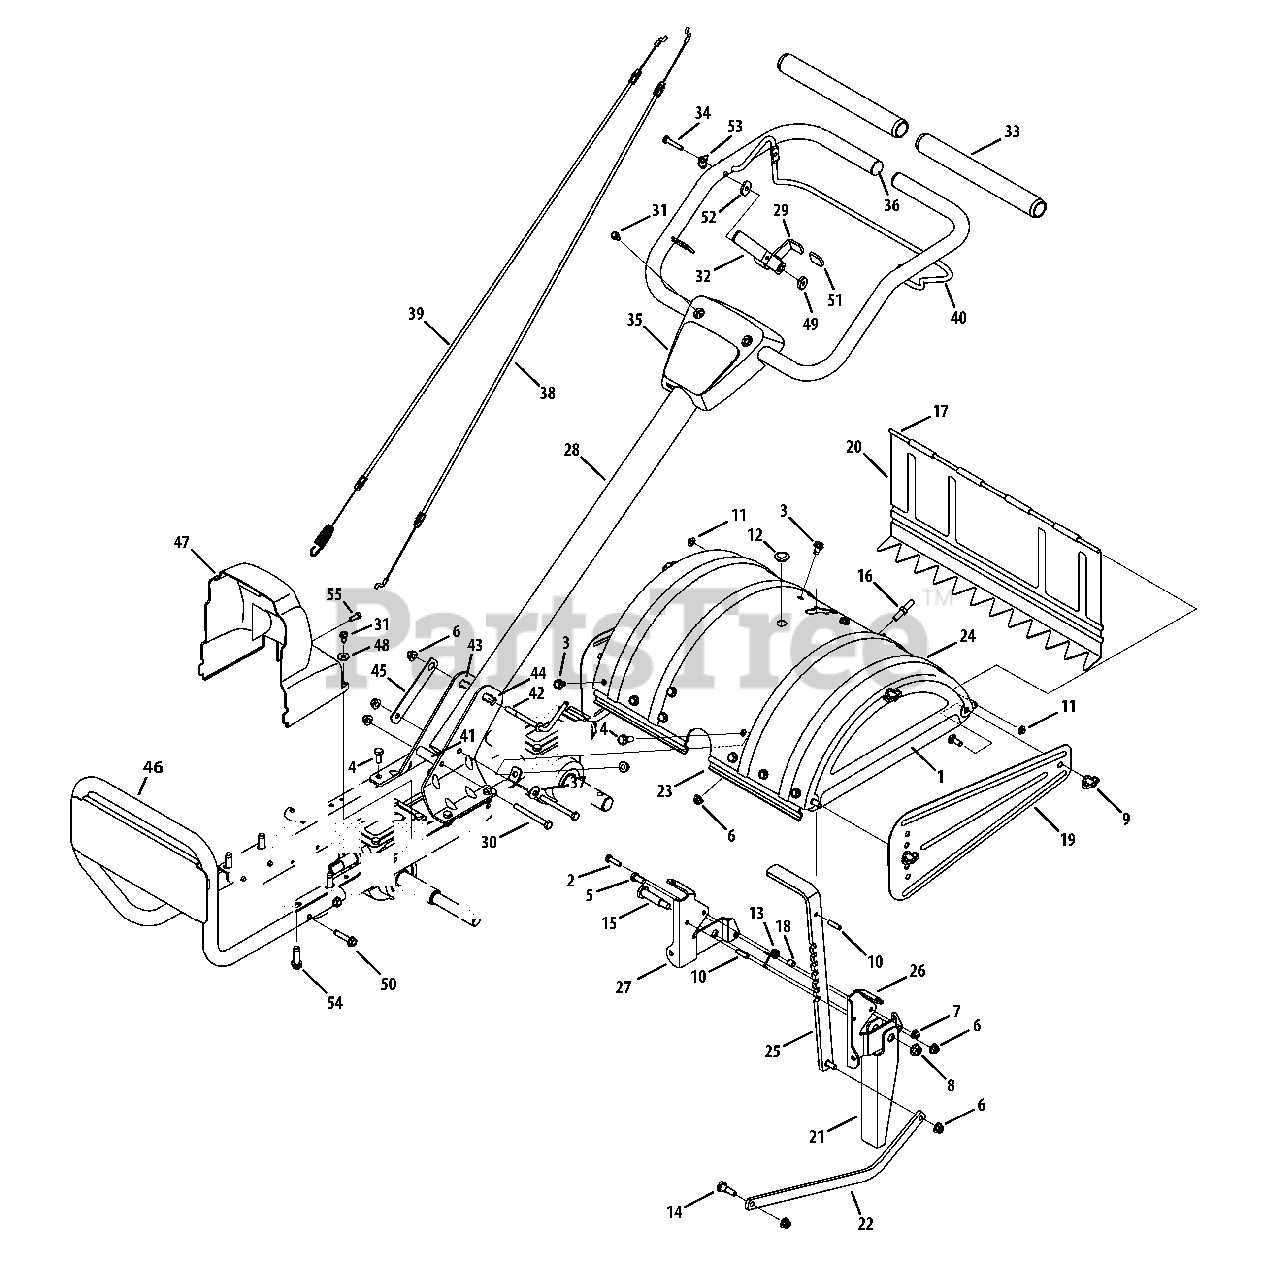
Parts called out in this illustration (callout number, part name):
1	End Cover Assembly
2	Hex Head Screw, 1/4-20 x 1
3	Hex Head Screw, 5/16-18 x .625
4	Hex Head Screw, 5/16-18 x .875
5	Hex Head Screw, 5/16-18 x .75
6	Nylon Hex Lock Nut, 5/16-18
7	Nylon Hex Lock Nut, 1/4-20
8	Flange Lock Nut, 3/8-16
9	Wing Nut, 5/16-18
10	Spirol Pin
11	Cap Nut, 1/4 Rod
13	Torsion Spring
14	Shoulder Screw, .405 x .435 5/16-18
15	Shoulder Screw, .498 x 1.635
16	Stop Screw
17	Tiller Flap Rod
20	Rear Tine Shield
21	Reverse Stop Arm
23	Tine Shield Mounting Bracket
25	Adjustable Depth Bar
26	Tail Bracket, LH
27	Tail Bracket, RH
28	Upper Handle Assembly
29	Reverse Handle Assembly
30	Hex Head Screw, 5/16-18 x 3.00
31	Self-Tapping Screw, 1/4-20 x 1/2
32	Handle Select
33	Foam Handle Grip
34	Hex Head Screw, 1/4-20 x 1.62
35	Handle Cover
36	Plug End
37	Bell Washer, .340 x .872 x .060
38	Reverse Cable
39	Forward Cable
40	Clutch Bail
41	Spacer, .322 x .625 x 2.00
42	Handle Crank
43	Handle Bracket, RH
44	Handle Bracket, LH
45	Retainer Nut Bracket
47	Belt Cover
48	Flat Washer, .28 x .74 x .063
49	Spacer, .375 x .165
50	Hex Head Screw, 5/16-18 x 1.50
51	Reverse Handle Grip
52	Flat Washer, .265 x .938 x .120
53	Saddle Washer, .320 x .930 x .060
54	SEMS Screw, 3/8-16
55	Self Tapping Screw, 1/4-14 x .625
